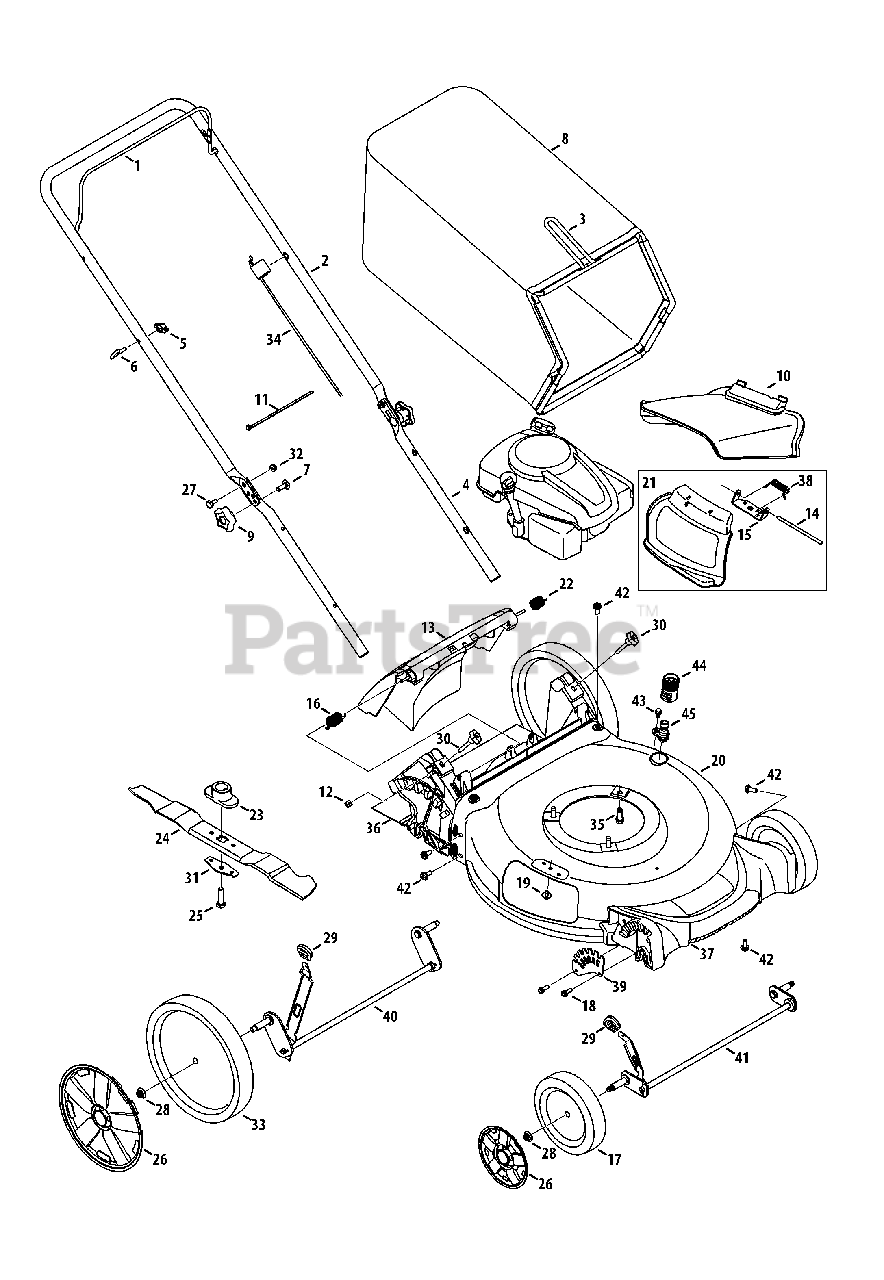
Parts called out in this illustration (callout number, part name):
1	Blade Control
2	Upper Handle
4	Lower Handle
5	Wing Nut
6	Rope Guide
7	Carriage Screw ,5/16-18
8	Grass Bag
9	Hand Knob
10	Side Chute
11	Cable Tie
12	Nut, Sq., 1/4-20
13	Rear Discharge Door Assembly
14	Hinge Pin
15	Chute Deflector Bracket
16	Torsion Spring - RH
17	Wheel, 7 x 2
18	Screw, 1/4-15 x .750
19	Screw, 1/4-20 x .500
20	Deck - 21"
21	Hinged Mulch Plug Assembly
22	Torsion Spring - LH
23	Blade Adapter
24	Mulching Blade
25	Screw , 3/8-24 x 1.50
26	Hub Cap - Front
26	Hub Cap - Rear
27	Sldr. Screw, .375 x .126 x 1/4-20
28	Flange Lock Nut, 3/8-16
29	Adjustment Lever Knob
30	Wing Nut
31	Blade Bell Support
32	Nut, Flange Lock, 1/4-20
33	Wheel, 11 x 2
34	Control Cable
35	TT Screw, 3/8-16 x 1.0
36	Trail shield
37	Front Cover
38	Torsion Spring
39	Front Height Adjuster Plate
40	Rear Axle Assembly
41	Front Axle Assembly
42	Screw, 5/16-14 x .750
43	Shldr. Screw, 1/4-20 x .50
44	Water Nozzle Adapter
45	Deck Wash Nozzle
